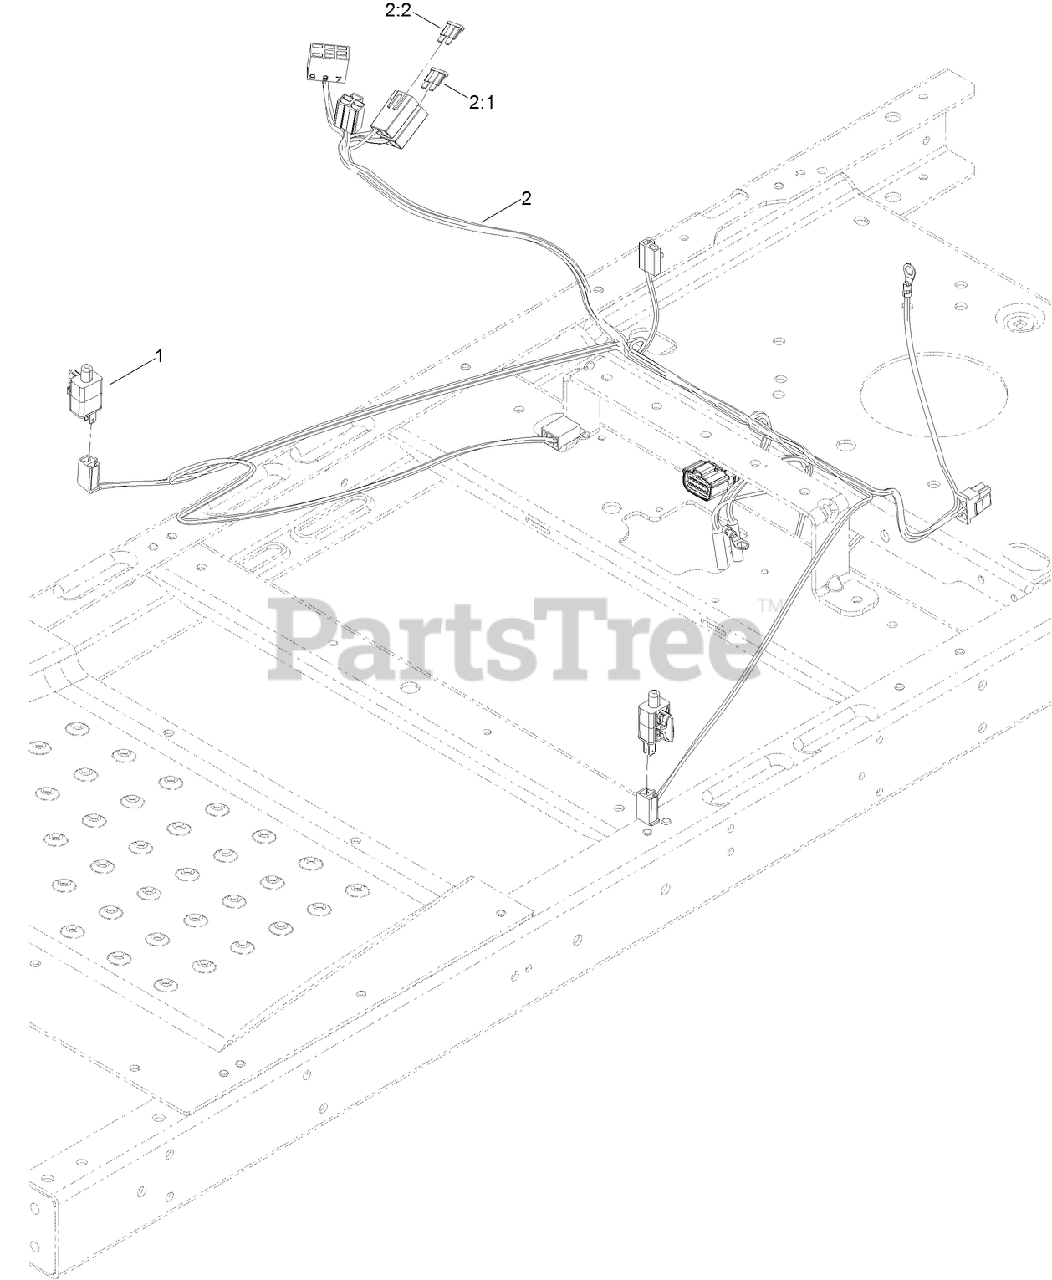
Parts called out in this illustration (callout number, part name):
1	SWITCH
2:1	FUSE-BLADE, 30 AMP
2:2	FUSE-BLADE, 25 AMP
